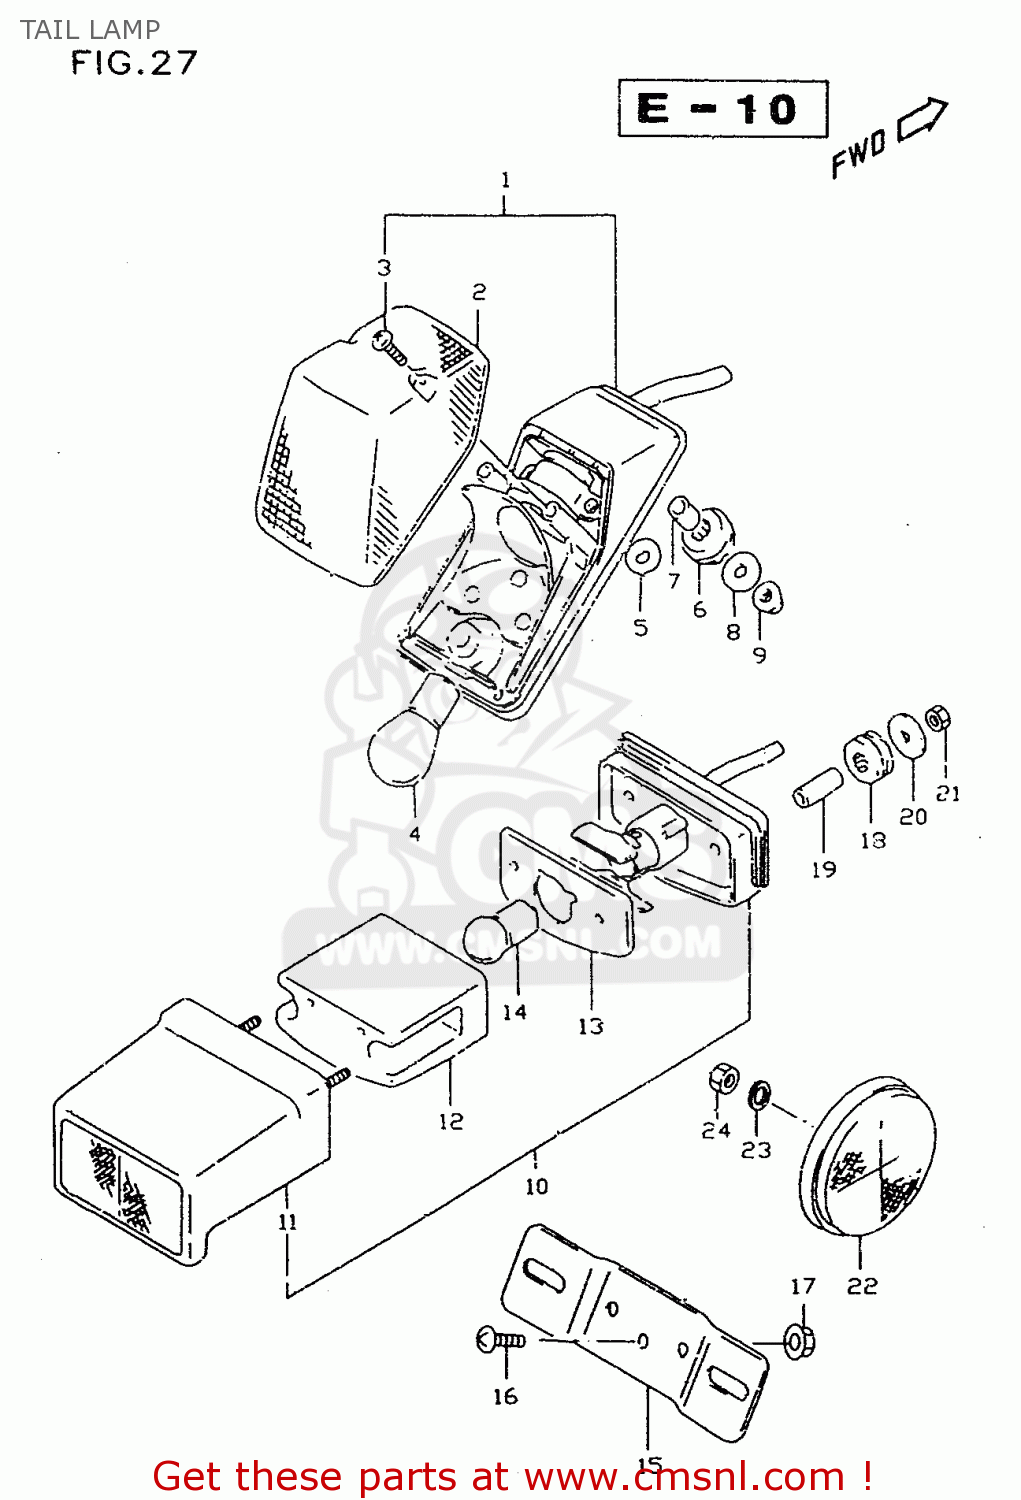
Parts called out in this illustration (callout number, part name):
1	LAMP ASSY,RR COMBINATION
2	LENS
3	SCREW
4	BULB(12V21/5W)
5	GASKET (NAS)
6	CUSHION
7	SPACER(6.4X9.2X12)
8	WASHER(6.5X20X1.6)
9	NUT 6MM
10	LAMP ASSY,LICENSE
11	REFLECTOR/COVER
12	LENS
13	GASKET,LICENSE LAMP (NAS)
14	BULB(12V5W,BF150-40160A)
15	PLATE,RR LICENSE
16	SCREW
17	NUT
18	CUSHION
19	SPACER(5.5X9.5X19.5)
20	WASHER(5.5X20X1.2)
21	NUT
22	REFLECTOR,REFLEX FR
23	LOCK,WASHER
24	NUT
